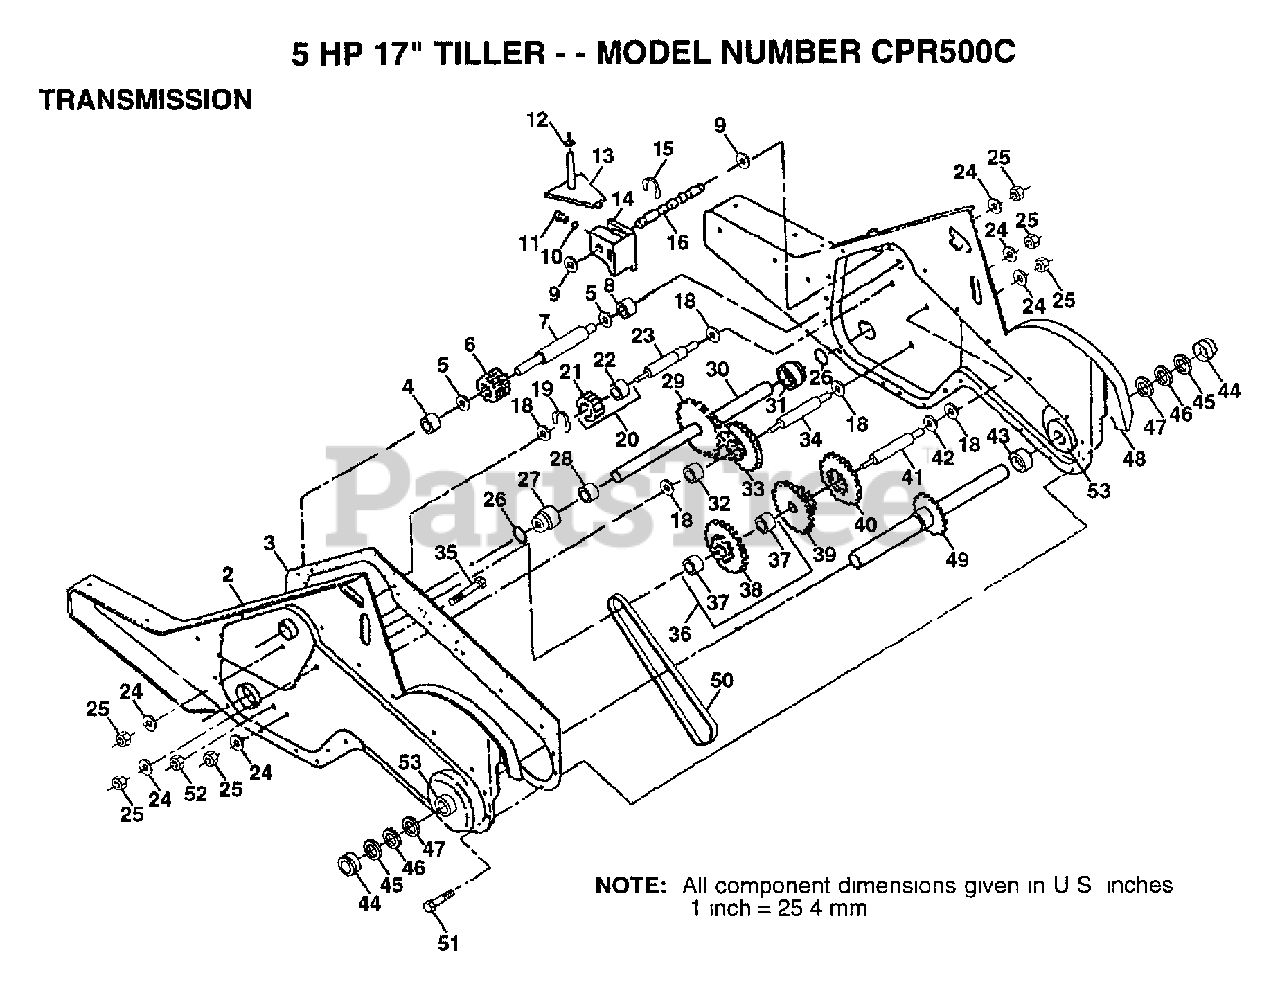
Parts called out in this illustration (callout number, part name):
3	GASKET TI
4	NEEDLE BRNG LT
5	"T, BEARING"
6	GEAR PINION INPUT
7	SHAFT-INPUT CRT
8	"TI, BEARING"
9	WASHER SEAL CRT
11	SPRING-SHIFT CRT
12	O-RING TI
13	BRACKET ASM SHIFT
14	SHIFT FORK TI
15	KLIP RING
16	SHAFT.SHIFT.4.250
18	WASHER
19	KLIP RING
20	GEAR ASSY CRT
21	GEAR-REV IDLR CRT
22	NEEDLE BEARING TI
23	SHAFT CRT
24	LOCKWASHER
25	NUT.ASF.HEX.7/16
26	O RING CRT
27	"CRT, BEARING"
28	BUSHING TI
29	CHAIN CRT
32	SPACER TI
33	SPRCKT 8 GEAR CRT
34	SHFT 2ND RED. CRT
35	SCRW WHIZ LOK CRT
36	SPROCKET ASM.
37	BEARING
39	GEAR TI
40	GEAR TI
41	REDUCTION SHFT TI
42	BRNG RACE
43	SPACER TI
44	CUP.FORMED.
45	RING SPIRAL CRT
46	SEAL RING RUBBER
47	OIL SEAL STD
49	TINE SHAFT
50	CHAIN.50 LINK TI
51	SCREW CRT
52	NUT.HEX.5/16-18
